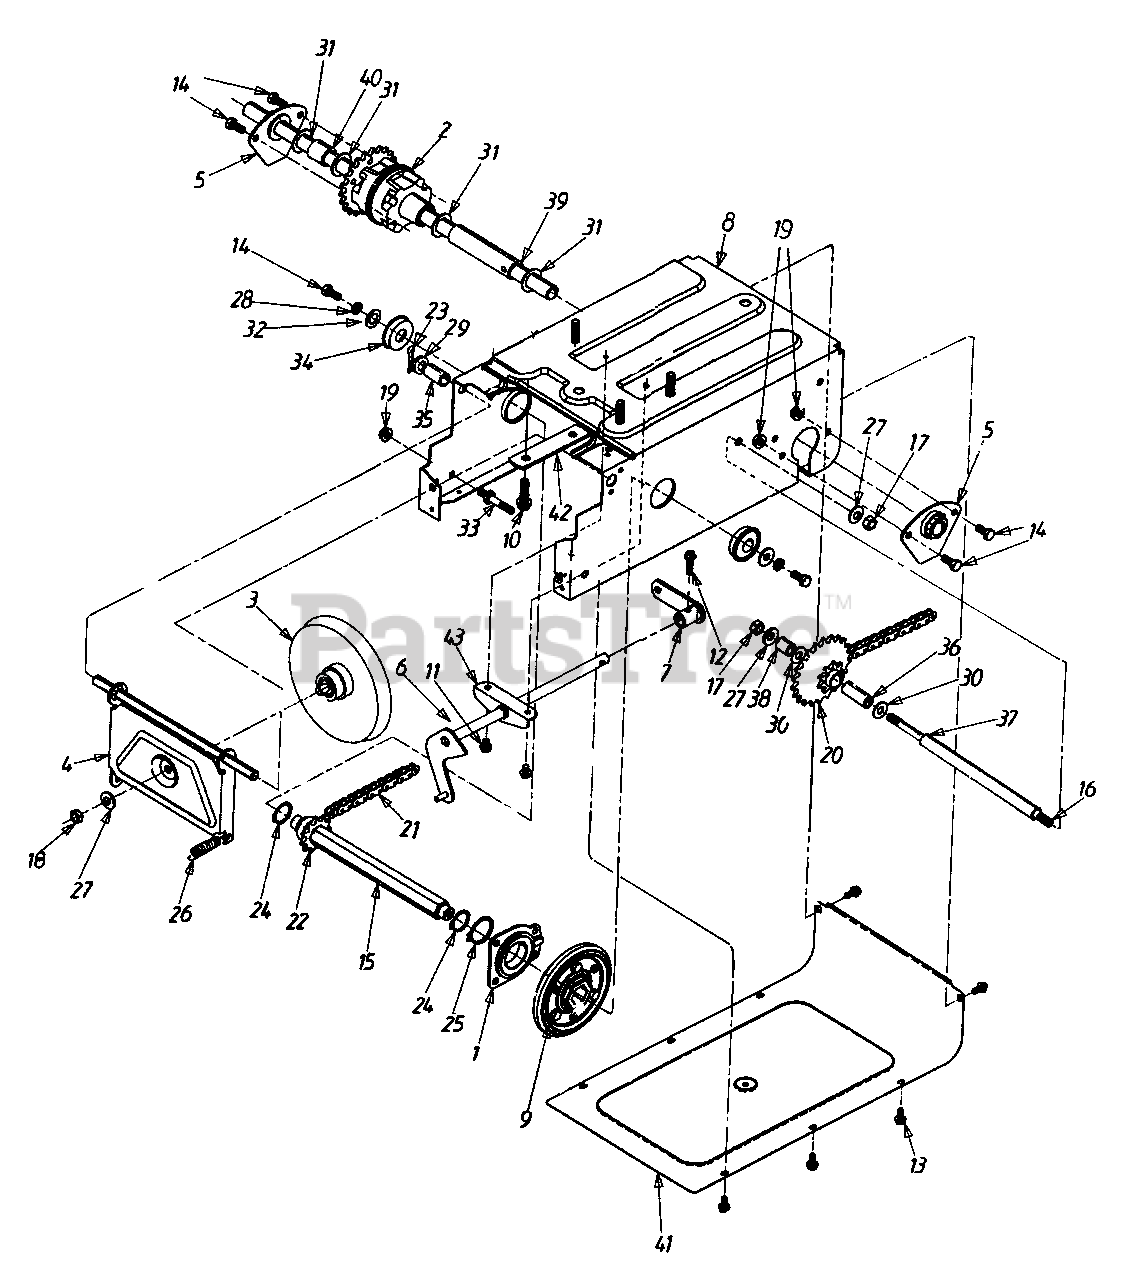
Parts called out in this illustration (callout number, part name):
1	BEARING ASSY-FRICTION WHEEL
2	DIFFERENTIAL ASSY COMP.
3	DISC-FRICTION WHEEL ASSY COMP.
6	SHAFT ASSY-SHIFT
9	WHEEL ASSY-FRICTION
10	SCREW-HEX SELF-TAP
11	SCREW-HEX WASHER
12	SCREW-HEX WASHER
13	SCREW-HEX
14	SCREW-HEX
15	SHAFT-HEX
16	SHAFT-JACK
17	NUT-HEX
18	NUT-HEX JAM
19	NUT-HEX FLANGE LOCK
20	SPROCKET K HUB
21	CHAIN
22	SPROCKET 11T
23	PIN-COTTER
24	RING-SNAP
25	RING-SNAP
26	SPRING-EXTENSION
27	WASHER-BELL
28	WASHER-LOCK
29	WASHER-FLAT
30	WASHER-FLAT
31	WASHER-FLAT
32	WASHER-FLAT
33	BOLT-IDLER
34	BEARING-BALL
35	SPACER
36	SLEEVE
37	SPACER
38	SPACER
39	SPACER
40	SPACER
